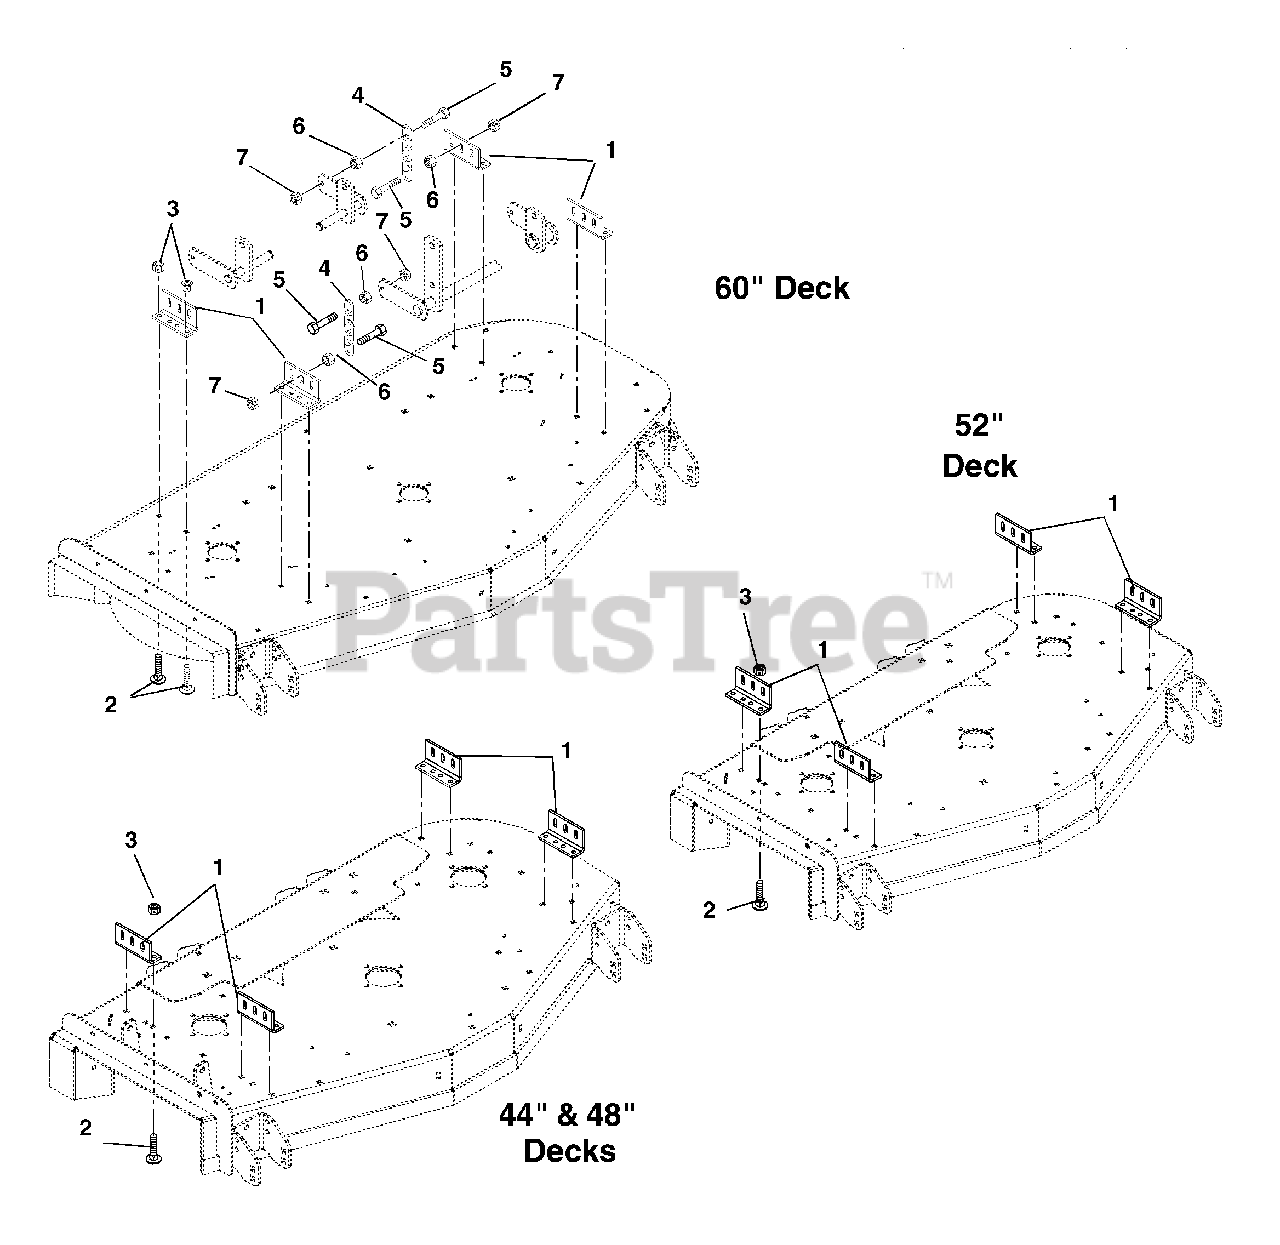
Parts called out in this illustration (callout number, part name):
1	Bracket, Mower Mounting
2	Bolt, Round Head Square Neck .38-16 x 1.00 Grade 2
3	Nut, Locking Top Flange .38-16
4	Chain, Link
5	Bolt, Hex .50-13 x 2.00 Grade 5
6	Nut, Spin Lock Flange .50-13
7	Nut, Locking Top Flange .50-13
